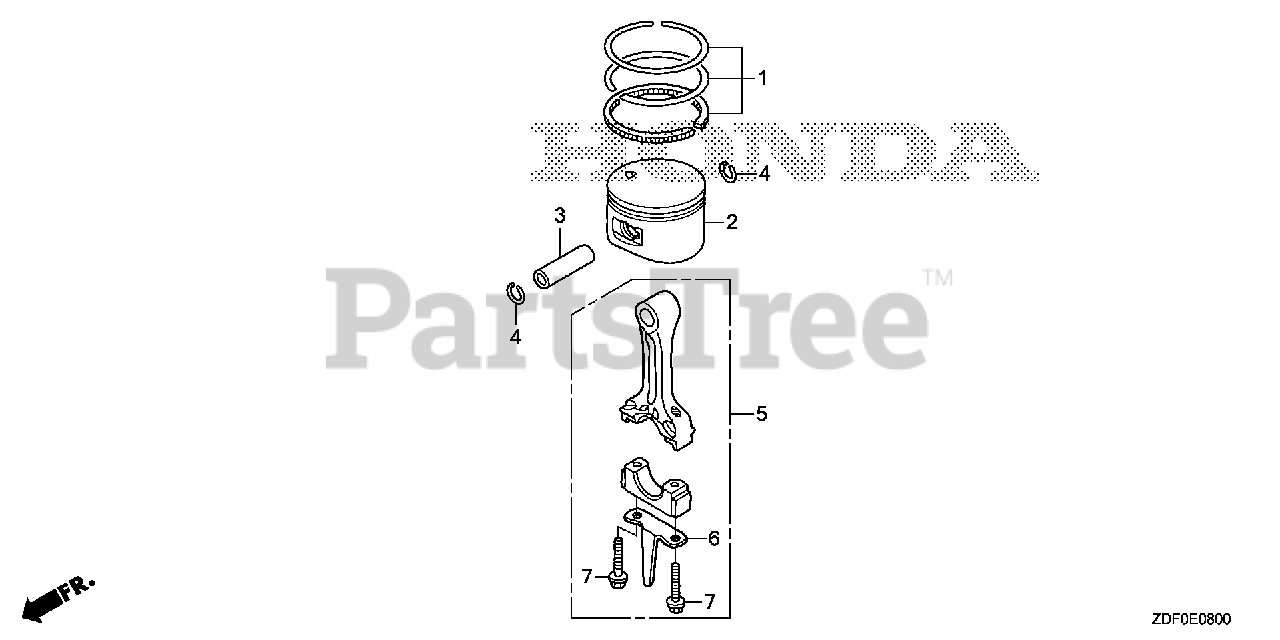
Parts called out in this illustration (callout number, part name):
1	RING SET, PISTON (STD)
2	PISTON (STD)
3	PIN, PISTON (10X33)
3	PIN, PISTON
4	CLIP, PISTON PIN (10MM)
5	ROD ASSY., CONNECTING
6	DIPPER, CONNECTING ROD
7	BOLT, CONNECTING ROD
